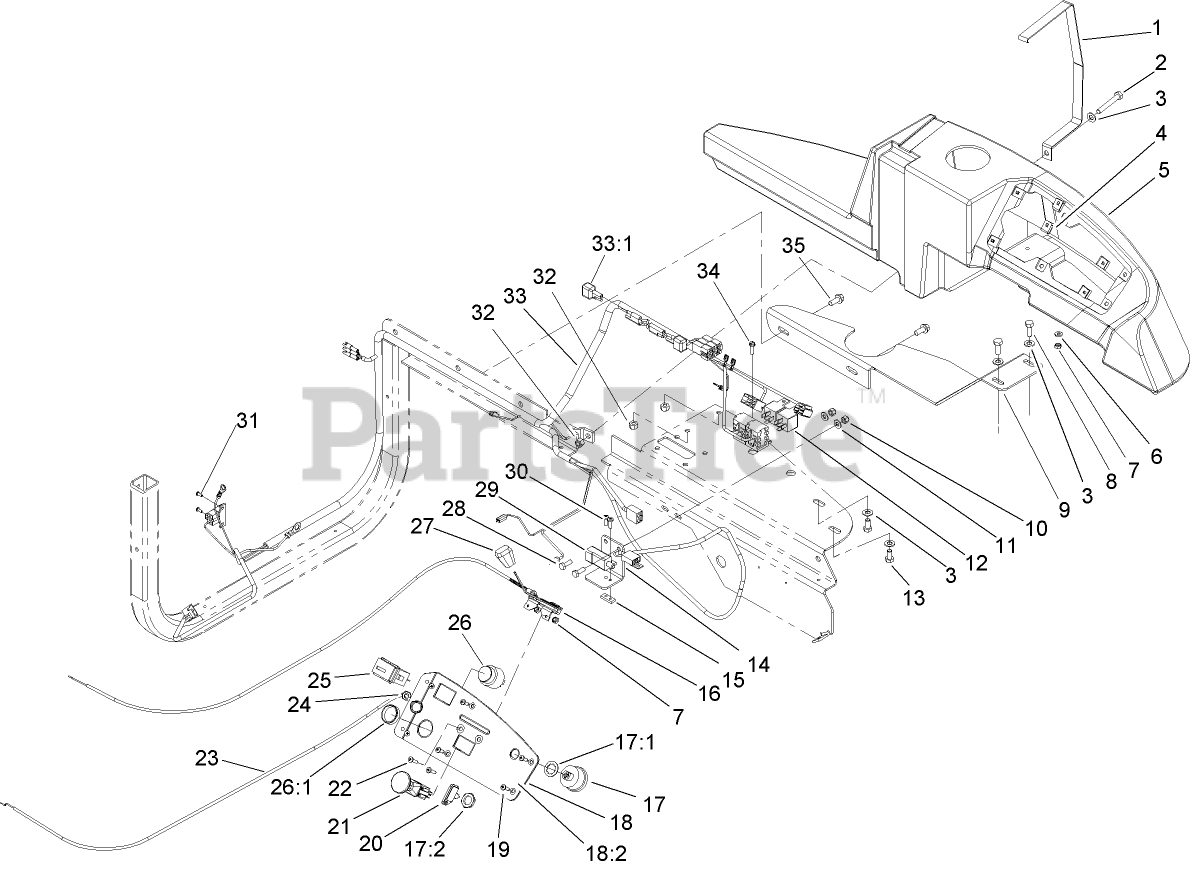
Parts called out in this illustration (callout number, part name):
1	STRAP-CONSOLE
2	SCREW-HH
3	WASHER-PLAIN
4	CLIP-TINNERMAN
5	CONSOLE
6	WASHER-FLAT
7	NUT-LOCK, NI
8	SCREW-HH
9	PLATE-SUPPORT, CONSOLE
10	NUT-LOCK, NI
11	WASHER-FLAT
12	RELAY
13	SCREW-HH
14	BRACKET-SWITCH
15	PLATE-TAPPED
16	THROTTLE CONTROL ASM
17	Key Switch ASM
17:1	WASHER-TOOTH, INTERNAL
17:2	NUT-HH
18	INSTRUMENT PANEL ASM
18:2	DECAL-INSTRUMENT
19	SCREW-PPH
20	KEY-IGNITION
21	SWITCH-DELTA
22	SCREW-PPH
23	CONTROL-CHOKE
24	NUT-HJ
25	HOURMETER
26	AUDIO ALARM ASM
26:1	NUT-PLASTIC, KNURLED
28	SCREW-HH
29	SWITCH
30	SCREW-PPH
31	SCREW-TAP
32	NUT-LOCK, NI
33	HARNESS-WIRE
34	SCREW-HWH
35	SCREW-HWHTF
